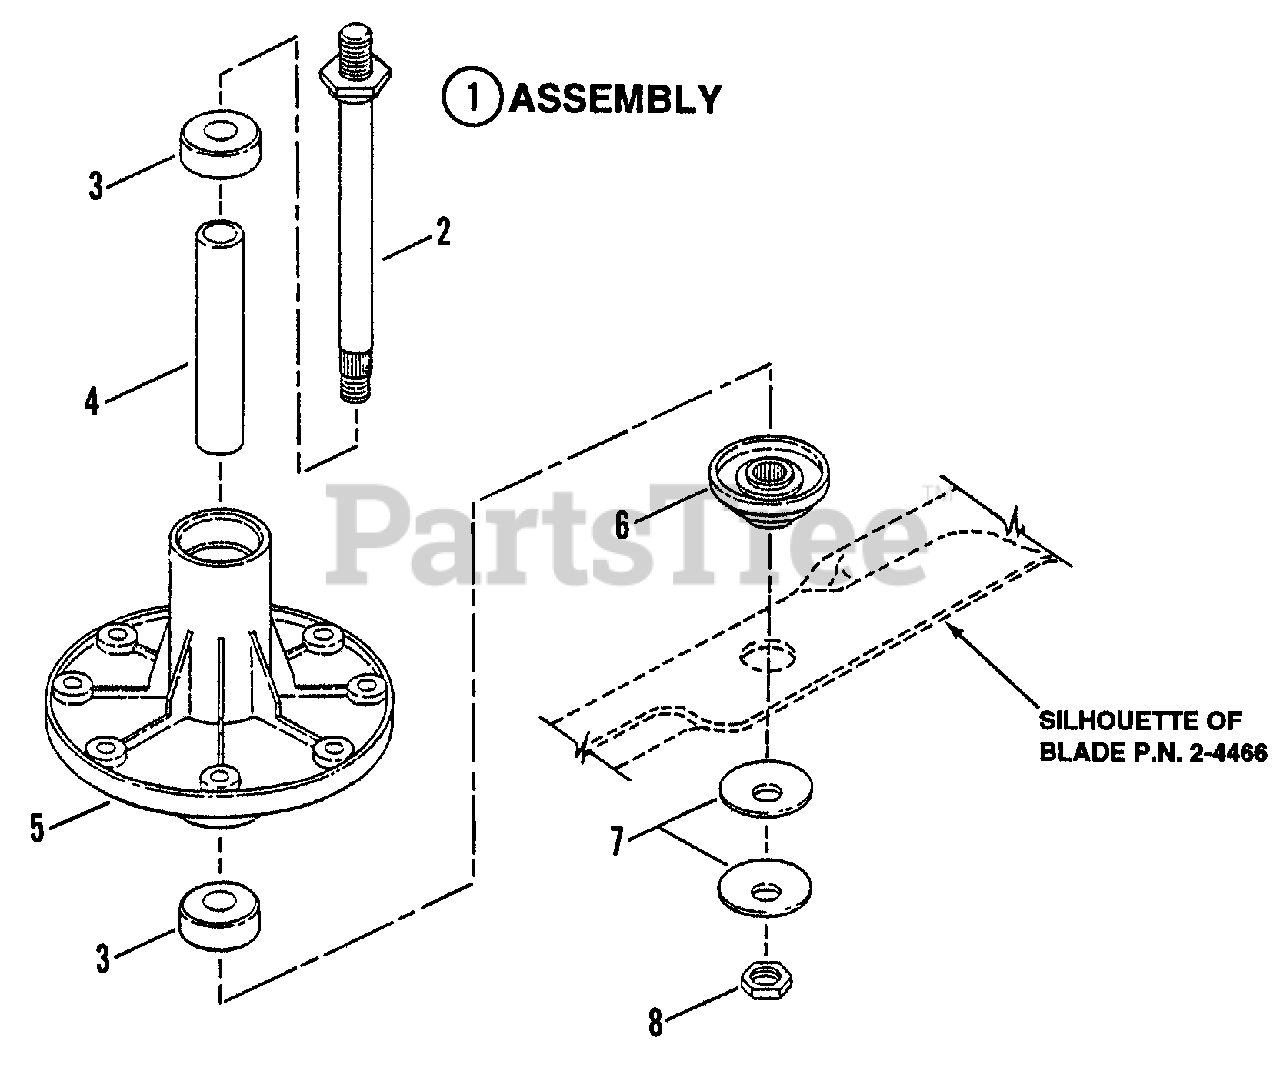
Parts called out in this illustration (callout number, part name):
1	ASSEMBLY, Spindle Housing, 38" Cutting Deck
2	SPINDLE, 7.019" Long
3	BEARING, Spindle
4	SPACER, Spindle Housing
5	HOUSING, Spindle
6	SPACER, Blade
7	WASHER, Bellville, 19/32" I.D. x 1 3/4" O.D.
8	NUT, 9/16-18 Hex Jam
